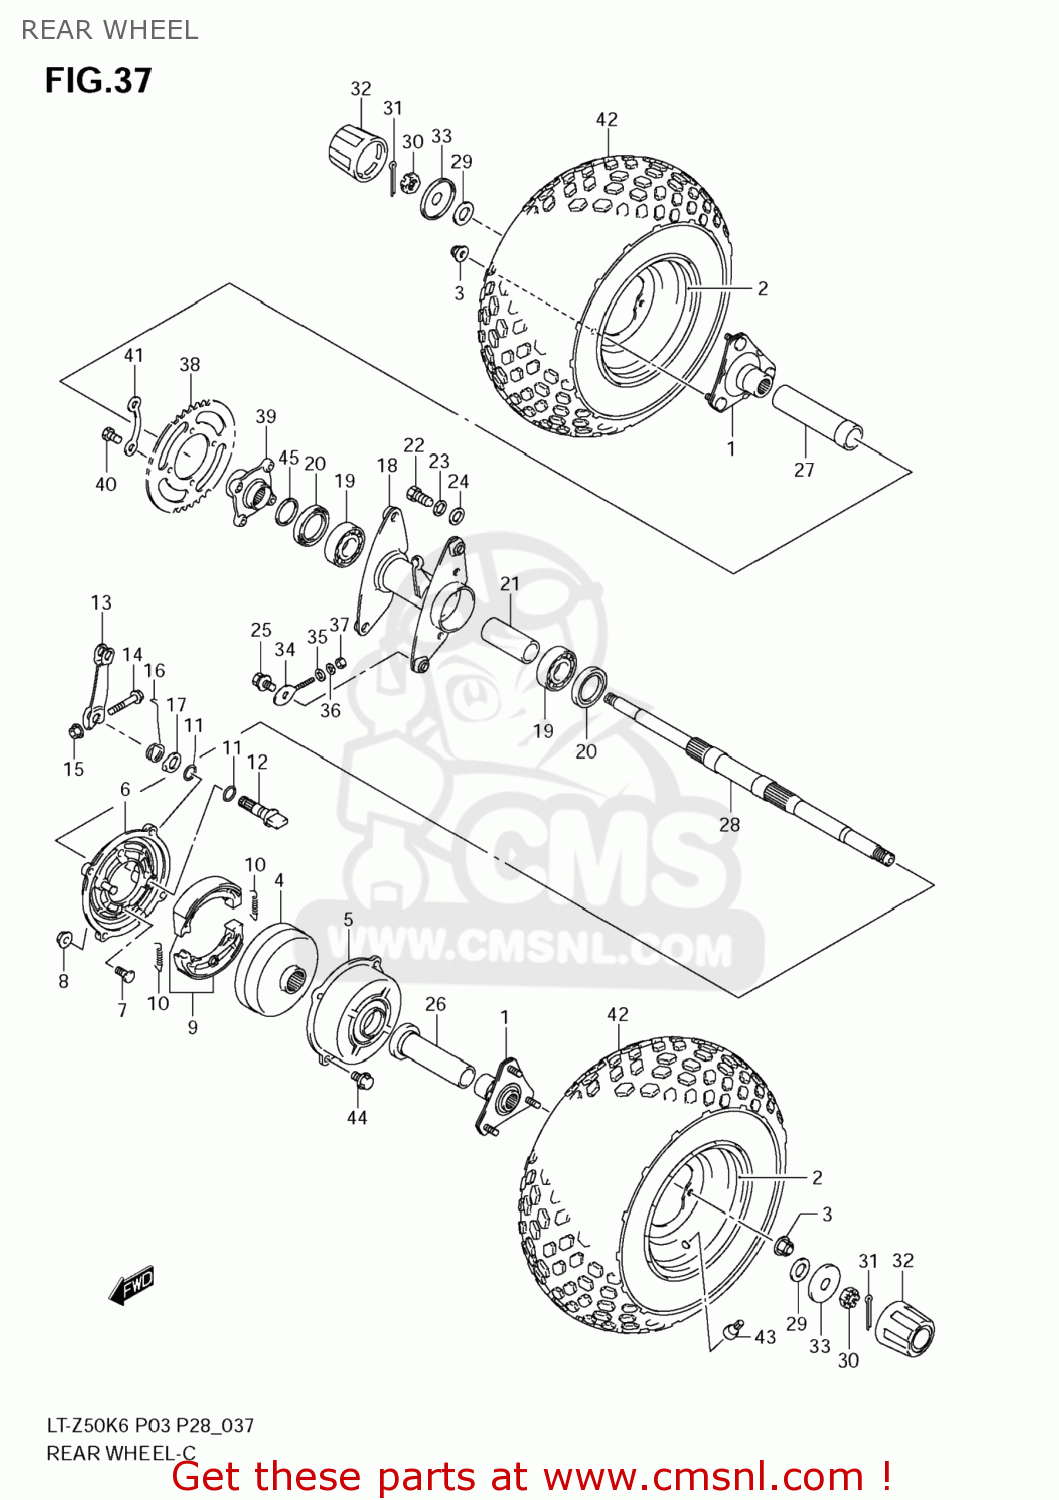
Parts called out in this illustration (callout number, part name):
1	HUB,RR WHEEL
2	RIM,RR WHEEL(7X6.0AT)
3	NUT
4	DRUM,RR BRAKE
5	COVER,RR BRAKE DRUM
6	PANEL,RR BRAKE ANCHOR
7	BOLT
8	NUT
9	SHOE SET,BRAKE (NAS)
10	SPRING
11	O RING(D:2.4,ID:11.8)
12	CAM,RR BRAKE
13	LEVER,RR BRAKE CAM
14	BOLT(6X32)
15	NUT
16	SPRING,RR BRAKE CAM LEVER
17	PLATE,BRAKE LINING INDICATOR
18	HOUSING,RR AXLE BEARING
19	BEARING(28X52X12)
20	SEAL,OIL(35X52X8)
21	SPACER,RR AXLE BRG
22	BOLT
23	WASHER,LOCK
24	WASHER
25	BOLT
26	SPACER,RR AXLE,R
27	SPACER,RR AXLE,L
28	AXLE,RR
29	WASHER,RR AXLE
30	NUT
31	PIN
32	CAP,WHEEL CTR
33	HOLDER,CTR CAP
34	ADJUSTER,CHAIN
35	WASHER
36	WASHER,LOCK
37	NUT
38	SPROCKET,RR
39	FLANGE,RR SPROCKET MOUNTING
40	BOLT(8X16)
41	WASHER
42	BAND
43	VALVE ASSY,WHEEL RIM(TR412)
44	BOLT
45	RING,SNAP
